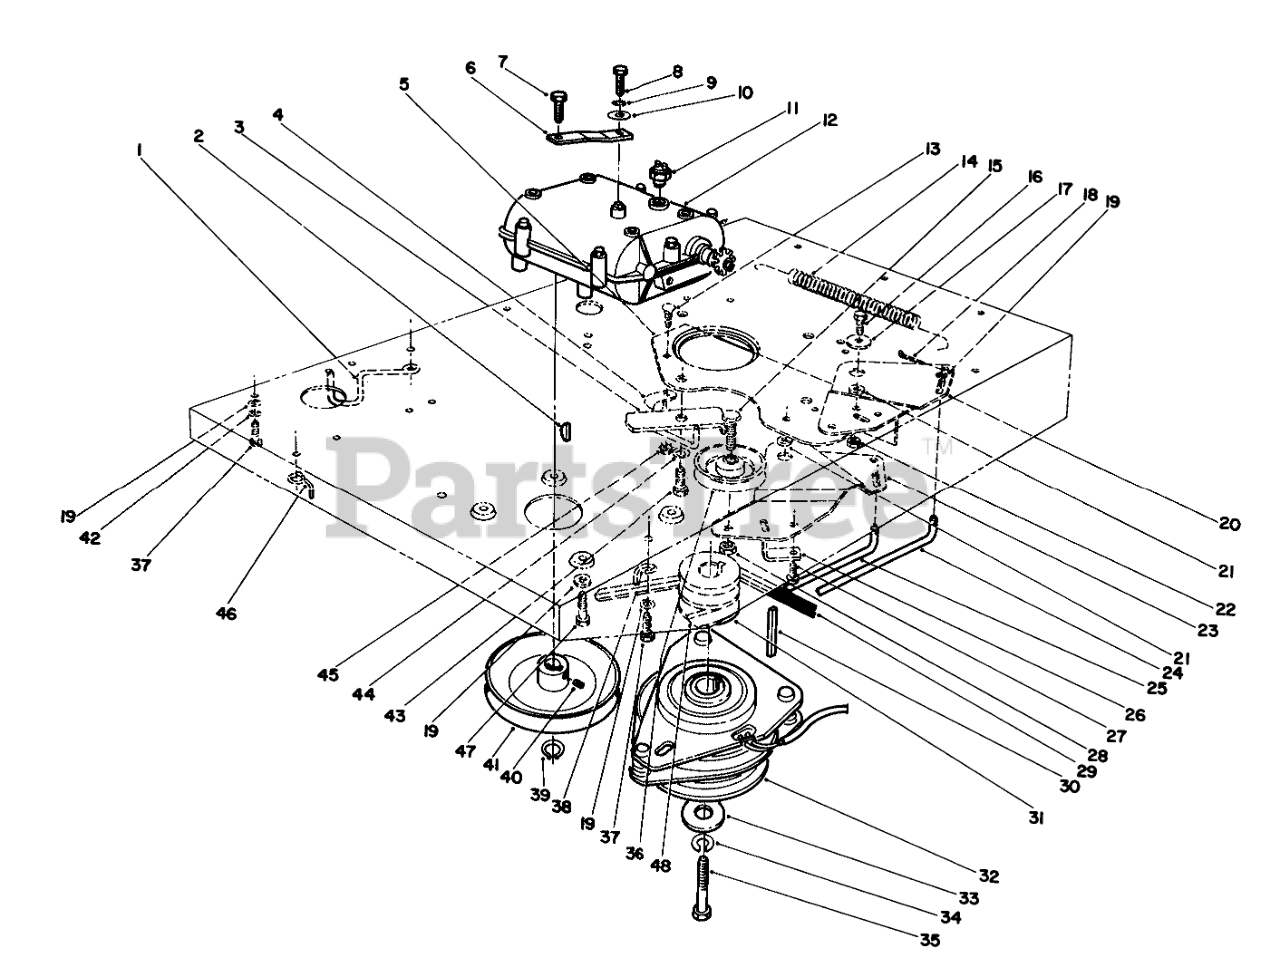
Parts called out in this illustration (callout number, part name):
1	BELT ROD
2	KEY-WOODRUFF
3	CLUTCH RETAINER WA B
4	CLIP-CLOSED, INSULATED
5	PANEL- PIVOT SUPPORT
6	LH SHIFT ARM
7	SCREW-HH
8	SCREW-HH
9	WASHER-LOCK
10	SPACER
11	NEUTRAL SWITCH
12	TRANSMISSION LH
13	SCREW-CARR
14	TRACTION SPRING
15	SCREW-LEVELER
16	SCREW-HH
17	WASHER-PIVOT
18	PIN-COTTER
19	WASHER-PLAIN
20	UPPER PIVOT BRACKET WA
21	SPACER-PIVOT, IDLER
22	NUT-LOCK, NI
23	LOWER PIVOT BRACKET WA
24	LEFT REAR PULL ROD
25	RIGHT REAR PULL ROD
26	BELT RETAINER
27	SCREW-HHFTF
28	NUT-LOCK, NI
29	V-BELT
30	KEY-STOCK
31	TRACTION DRIVE PULLEYB
32	CLUTCH/BRAKE
33	WASHER-CLUTCH
34	WASHER-LOCK
35	SCREW-HH
36	Idler
37	SCREW-HH
38	BELT GUIDE
39	RING-SNAP, EXTERNAL
40	SCREW-SET, HSH
41	PULLEY-TRANSMISSION
42	WASHER-LOCK
43	SCREW-HH
44	WASHER-BELLEVILLE
45	NUT-KEPS
46	BELT GUIDE
47	Screw-HH
48	V-BELT, 38" DECK
